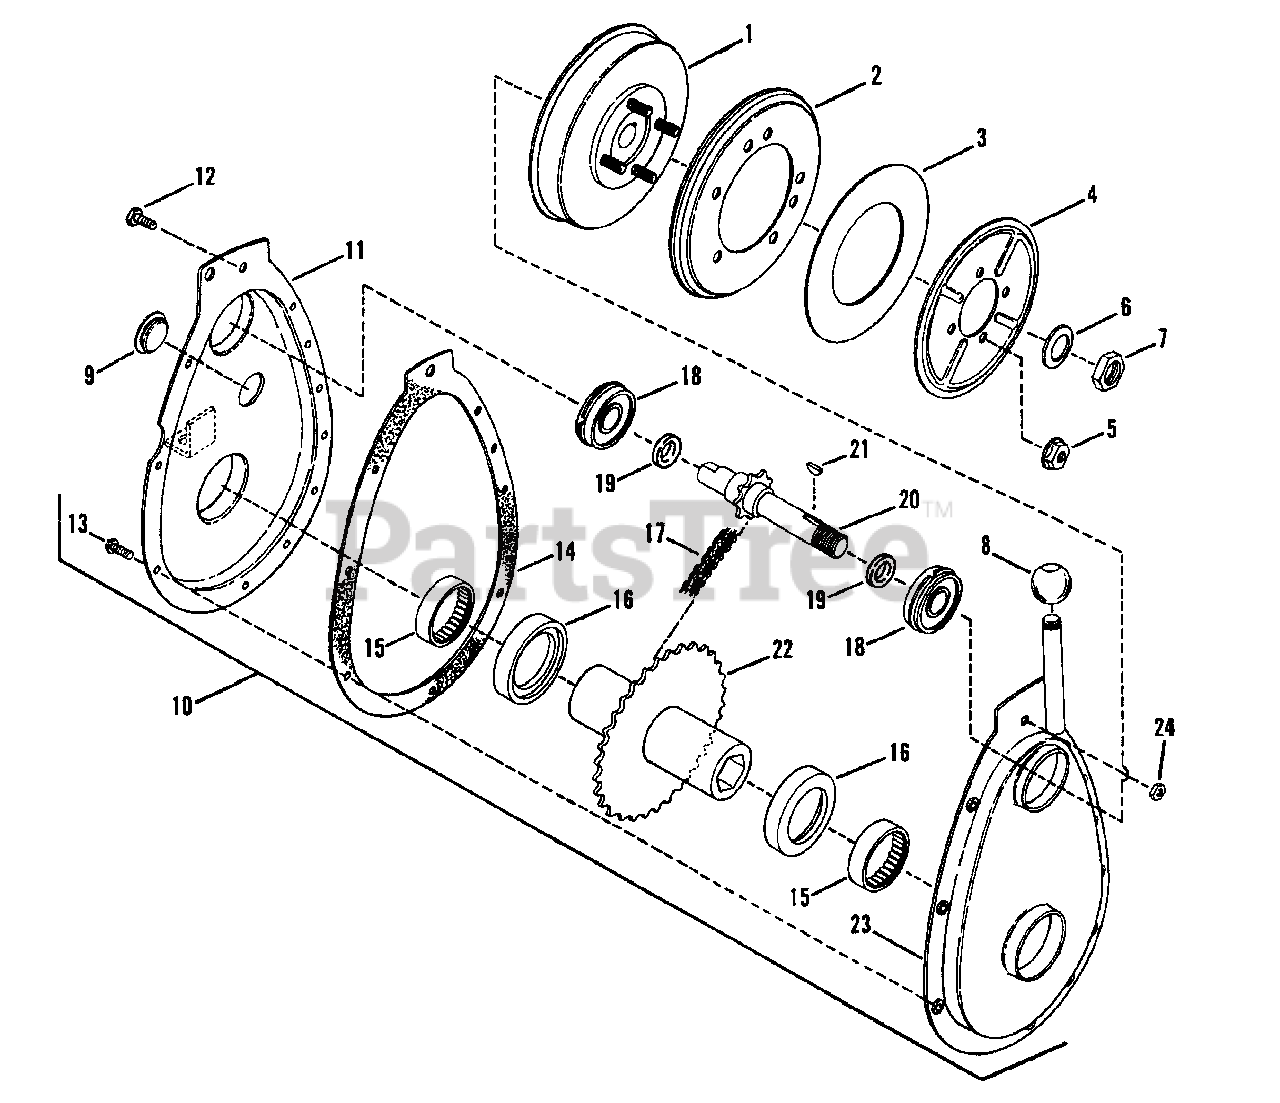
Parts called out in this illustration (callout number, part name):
1	HUB, Driven Disc
2	DISC, Driven
3	WASHER, Thrust
4	PLATE
5	NUT, 5/16-18 Hex Flange Lock, Grade 5
6	WASHER, Belleville
7	NUT, 5/8-18 Nyloc
8	BUSHING, Primary Clutch Ball
9	PLUG, Oil Fill & Check
10	ASSEMBLY, Primary Chain Case
11	COVER, Chain Case
12	SCREW, 1/4-20 x 5/8" Hex Head Cap, Gr. 5
13	SCREW, #10-24 x 1/2" Hex Washer Self-Tap (Torx)
14	GASKET, Case/Cover
15	BEARING, Needle
16	WASHER, Thrust
17	CHAIN
18	BEARING, Ball
19	"O"-RING
20	SPROCKET & SHAFT
21	KEY, Woodruff
22	HUB & SPROCKET
23	COVER, Sprocket
24	NUT, 1/4-20 Hex Center Lock, Gr. B or 5
